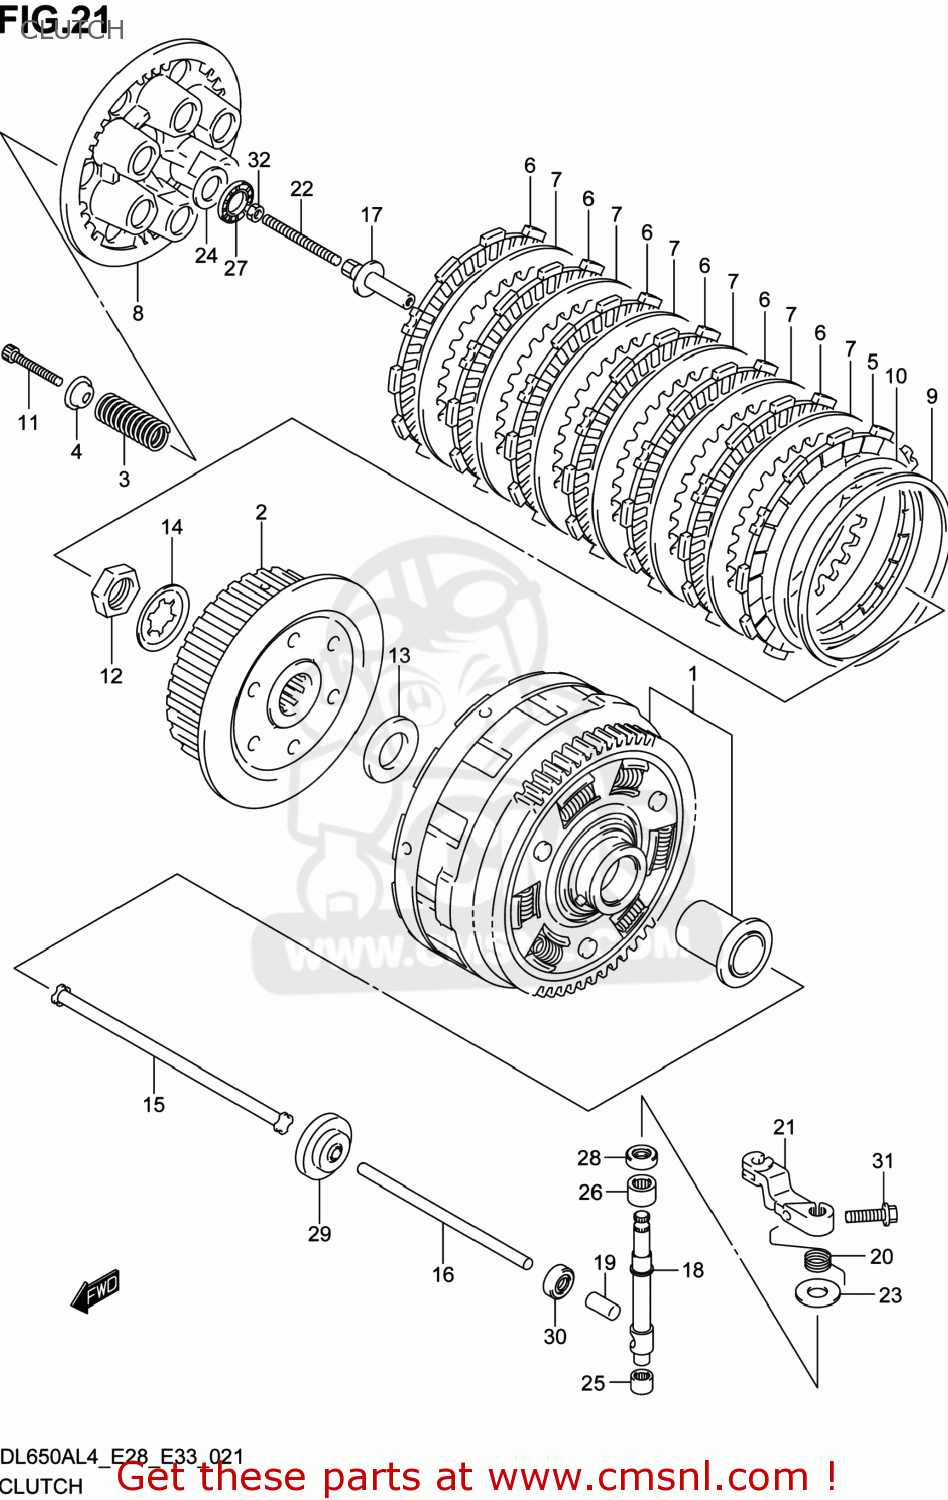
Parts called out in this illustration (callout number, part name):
1	GEAR ASSY,PRI DRIVEN
2	HUB,CLUTCH SLEEVE
3	SPRING,CLUTCH
4	WASHER
5	PLATE,CLUTCH DRIVE NO.2 (NAS)
6	PLATE,CLUTCH DRIVE (NAS)
7	PLATE,CLUTCH DRIVEN(T:1.6) (NAS)
8	DISC,CLUTCH PRESSURE
9	SEAT,WAVE WASHER
10	WASHER,CLUTCH PLATE WAVE
11	BOLT,CLUTCH SPRING
12	NUT
13	WASHER(20X36X3)
14	WASHER,LOCK
15	ROD,PUSH,R
16	ROD,CLUTCH PUSH,L
17	PIECE,CLUTCH PUSH
18	CAMSHAFT,CLUTCH RELEASE
19	CAP,CLUTCH PUSH ROD
20	SPRING,CLUTCH RELEASE RETURN
21	ARM,CLUTCH RELEASE
22	SCREW(6X73)
23	WASHER(10.5X24X1)
24	WASHER(15.5X28X1)
25	BEARING(10X14X10)
26	BEARING(12X18X12)
27	BEARING(15X28X2)
28	SEAL,OIL(10X20X6)
29	SEAL,OIL(6X34X10.5)
30	SEAL,OIL(10X17X5)
31	BOLT
32	NUT
